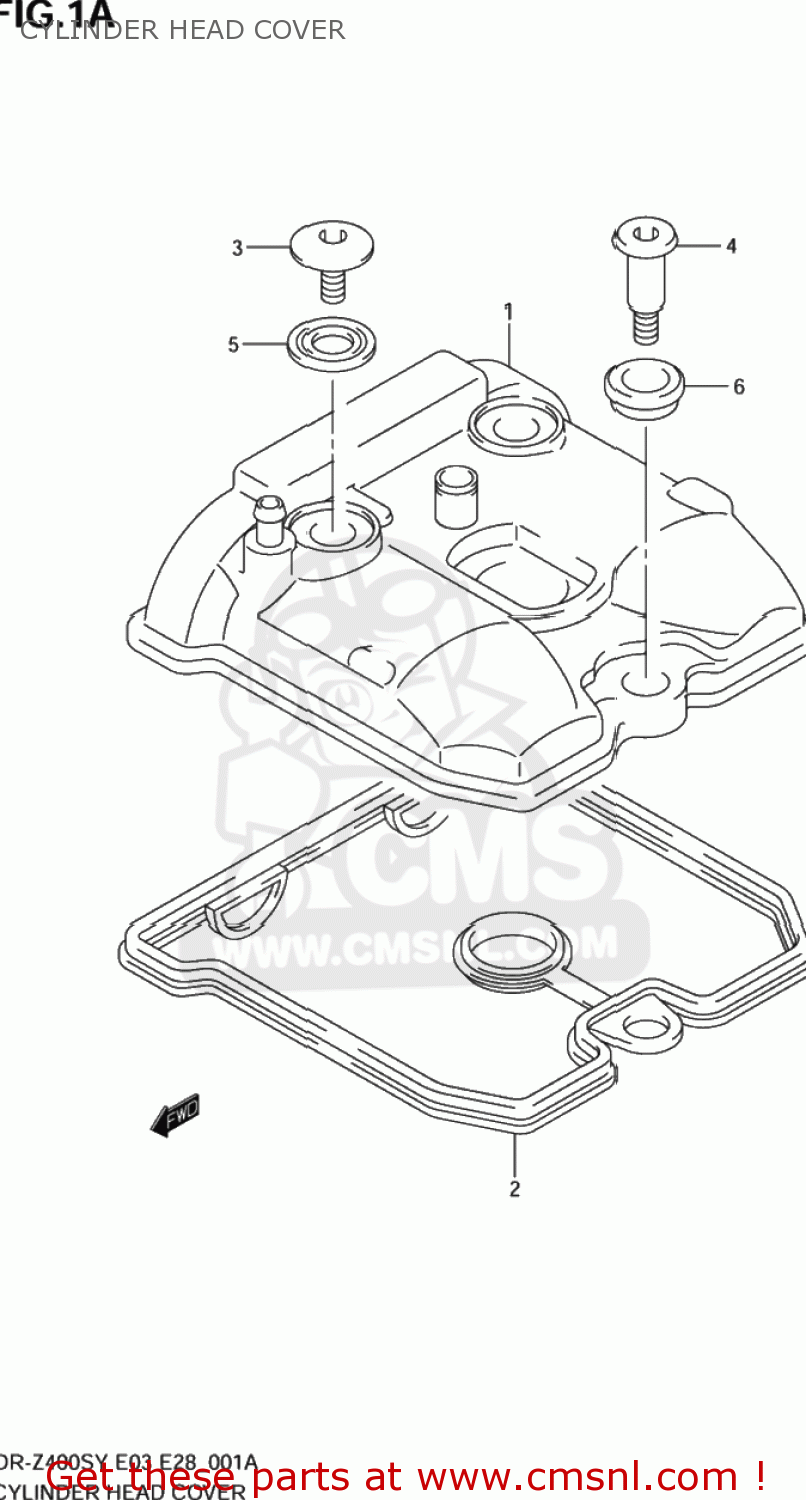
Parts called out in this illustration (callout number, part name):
1	COVER,CYLINDER HEAD
2	GASKET,CYL HEAD COVER (NAS)
3	BOLT(7X17.5)
4	BOLT(7X31)
5	WASHER(10.6X25.5X2.3)
6	CUSHION,HEAD COVER BOLT
